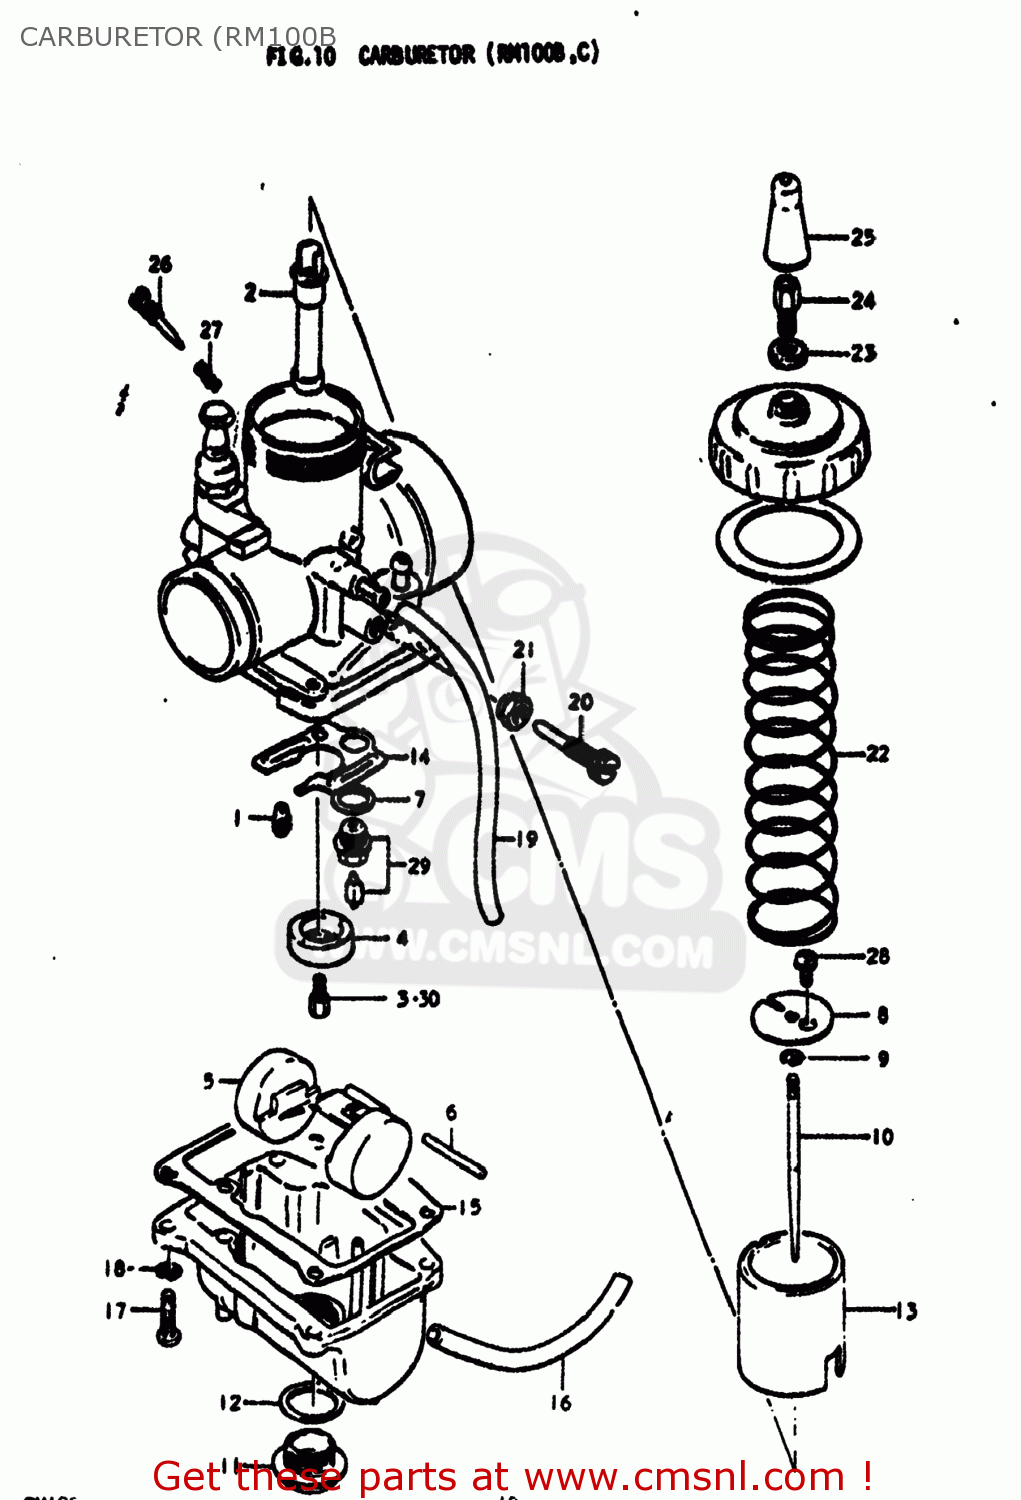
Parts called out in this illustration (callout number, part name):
0	CARBURETOR ASSEMBLY
1	JET
2	JET,NEEDLE
3	JET
4	RING
5	FLOAT
6	PIN,FLOAT
7	GASKET,MAIN JET HOLDER (NAS)
8	CLIP
9	CLIP
10	NEEDLE JET
11	SCREW,GUIDE
12	O RING,DRAIN PLUG
13	VALVE,THROTTLE
14	PLATE
15	GASKET,FLOAT CAHMBER (NAS)
16	HOSE
17	SCREW
18	LOCK WASHER
19	HOSE
20	SCREW
21	NUT
22	SPRING
23	NUT
24	ADJUSTER,CABLE
25	CAP
26	SCREW,PILOT AIR
27	SPRING
28	SCREW
29	VALVE ASSY,NEEDLE
30	JET
